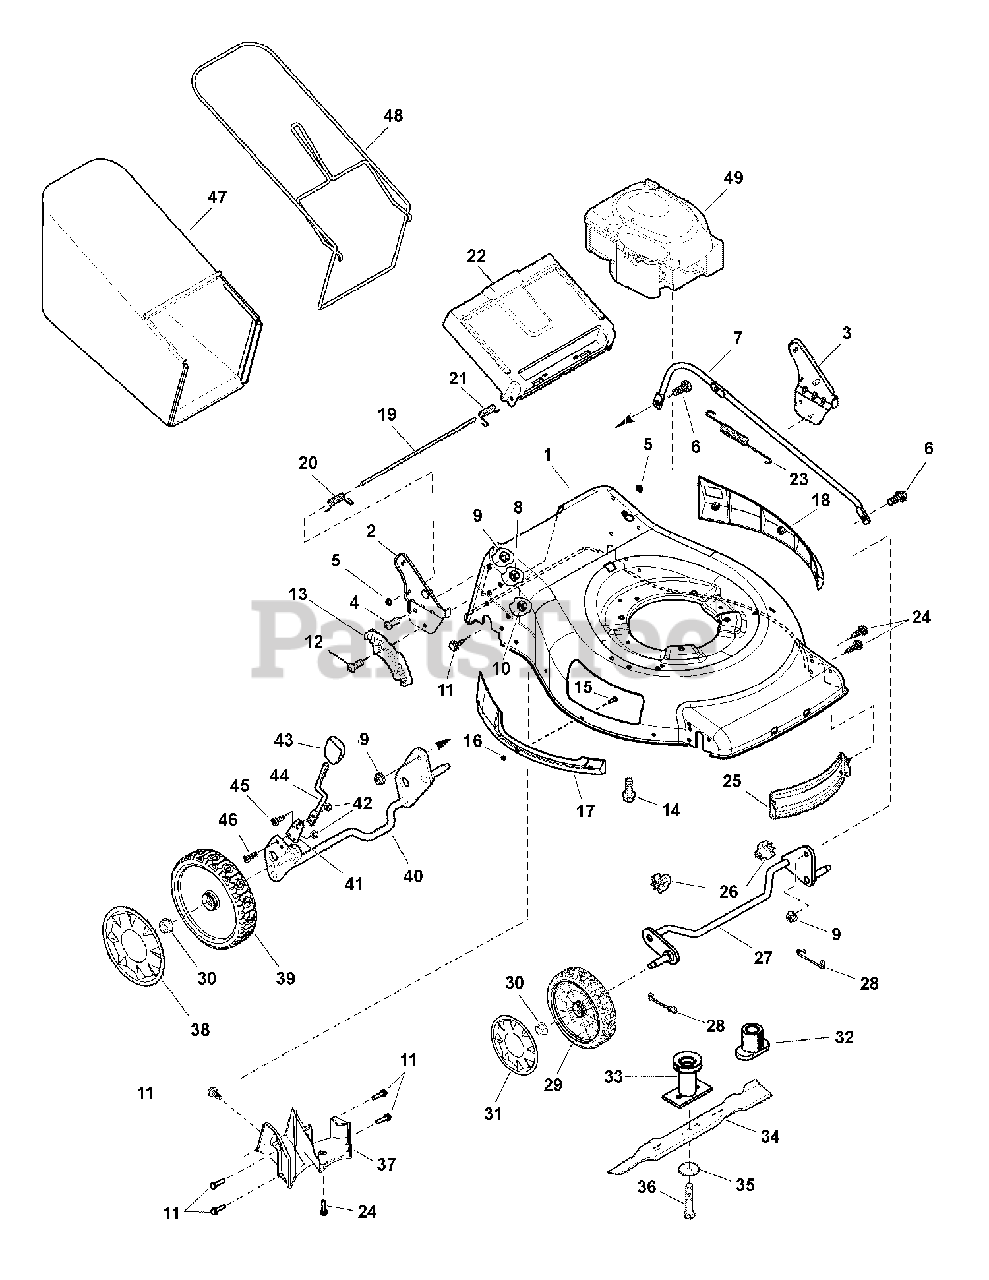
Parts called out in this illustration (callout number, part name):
1	HOUSING ASSEMBLY, 19" SD
2	HANDLE BRACKET, Assembly, RH - Black
3	HANDLE BRACKET, Assembly, LH
4	SCREW, 5/16-18 x 1.1, Hex Washer
5	NUT, Push, 1/4 BZ
6	BOLT, Hex Washer Head Shoulder, 5/16-18
7	LIFTER LINK, 19"
8	LOCKNUT, M8 Nyloc
9	NUT, 5/16-18, Fange Lock, BZ
10	NUT, Flange Lock, 1/4-20, BZ
11	SCREW, 1/4" HI-LO X .75
12	BOLT, Hex Socket Head, M8 x 1.25
13	INDEX BRACKET, Height, Standard Wheel
14	SCREW, HWST, 3/8 C X1 BZ
15	RIVET, Blind, 5MM X 12MM
16	WASHER, Flat, M8 ID X 0.5 OD
17	SIDE GUARD, RH, Mulching
18	SIDE GUARD ASSEMBLY, LH, Black
19	ROD, Rear Door
20	SPRING, Torsion, RH
21	SPRING, Torsion, LH
22	DOOR, Rear 19 EU Black
23	SPRING, Extension
24	SCREW, 1/4"-20 X 1/2" Taptite Pan Head
25	BAFFLE, Front, 19"
26	BUSHING, Front SLA
27	AXLE, Front Crossbar Weldment, 19"
28	SPRING CLIP, Front Axle Crossbar
29	WHEEL ASSEMBLY, Front, Ball Bearing, 175MM (5.6"), Tread III
30	LOCKNUT, 3/8-16, Hex Flange Top Lock
31	HUBCAP, Front, 175MM, Style 3, Silver 5.56" OD
32	ADAPTER, Blade, Push
33	ADAPTER, Blade, Self-Propelled
34	BLADE, 19" Low Lift
35	WASHER, Belleville 7/16 ID
36	BOLT, 3/8-24 x 2 Gr. 8
37	BAFFLE, Rear, 19, Plastic
38	HUBCAP, Rear, 200MM, Style 3, Silver 7.1" OD
39	WHEEL ASSEMBLY, Rear, Self-Propelled, 200MM (7.1"), BBSP TREAD III
39	WHEEL ASSEMBLY, Rear, Push, Ball Bearing, 200MM (7.1"), Tread III, SL
40	AXLE, Rear Crossbar Weldment
41	SPRING, Height Adjustment Handle
42	NUT, Nyloc, M5 X 0.8
43	KNOB, Height Adjust, Style ll
44	LEVER, Height Adjuster
45	SCREW, M5-0.8 X 12.5, Torx
46	SCREW, T-25 Torx Head, M5 x 0.8 x 14
47	BAG, 19, 70L
48	BAG FRAME, Weldment, 70L
49	* ENGINE, B&S, 550 Series, 10T802-0155-B1
49	* ENGINE, B&S, 675 Series, 126T02-0318-B1
